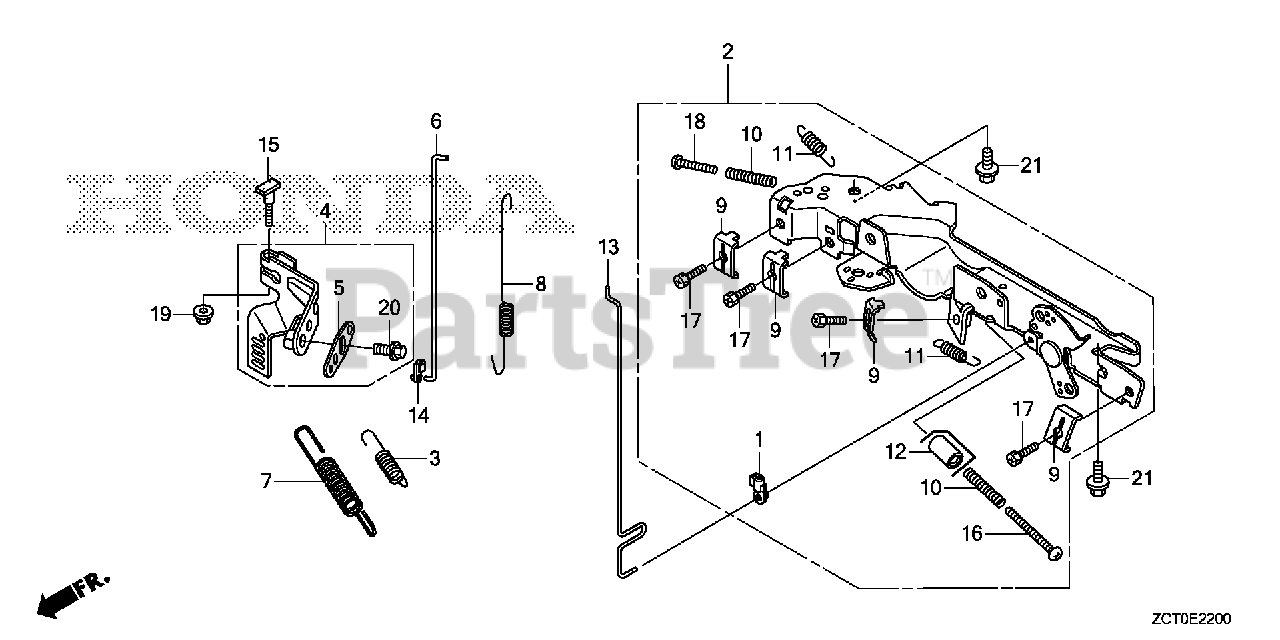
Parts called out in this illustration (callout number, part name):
1	JOINT, ROD
2	CONTROL ASSY.
3	SPRING, STARTER
4	ARM, GOVERNOR
5	ARM, SUB
6	ROD, GOVERNOR
7	SPRING, GOVERNOR
8	SPRING, THROTTLE RETURN
9	HOLDER, CABLE
10	SPRING, CONTROL ADJUSTING
11	SPRING, CABLE RETURN
12	COLLAR, STOPPER
13	ROD, CHOKE CONTROL
14	BUSH, LINKAGE
15	BOLT, GOVERNOR ARM
16	SCREW, RECESSED (5X45)
17	BOLT, RECESSED (5X16)
18	SCREW, PAN (5X30)
19	NUT, FLANGE (6MM)
20	BOLT, FLANGE (6X10)
21	BOLT, FLANGE (6X14)
